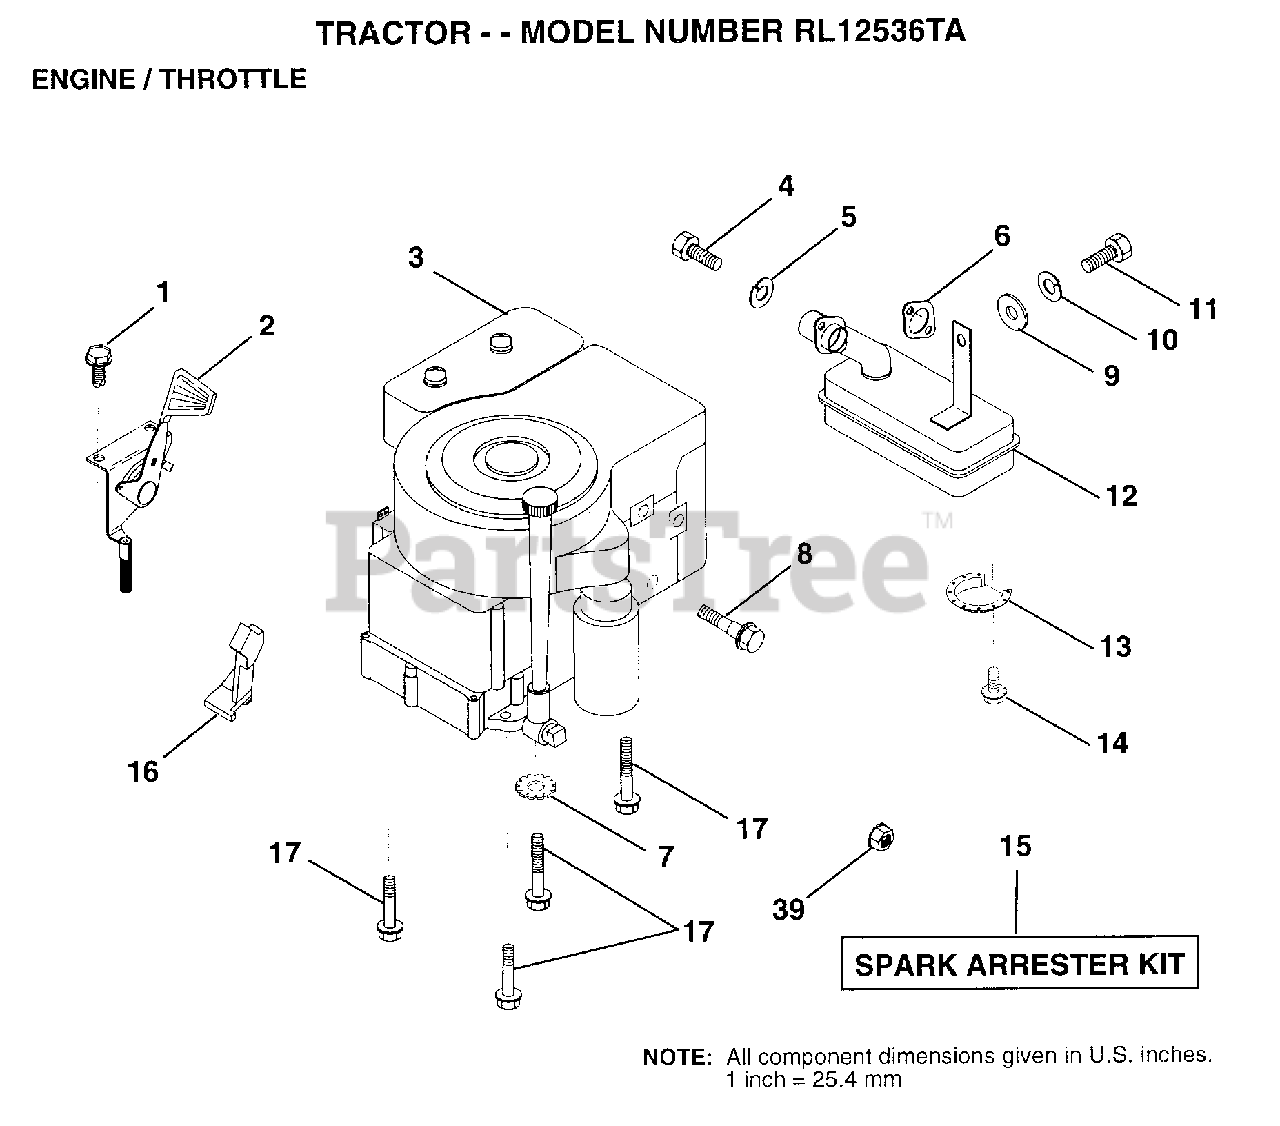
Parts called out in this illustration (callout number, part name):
1	SCREW.1/4-20X1/2
4	SCREW
5	LOCKWASHER
6	GASKET ENG 1 313 LD TIN PLATED
7	LOCKWASHER
8	SHOULDER BOLT ST
10	LOCKWASHER
11	BOLT LT
13	DEFLECTOR.222573
16	STOP.THROTTLE
17	SCREW LT
39	NUT
